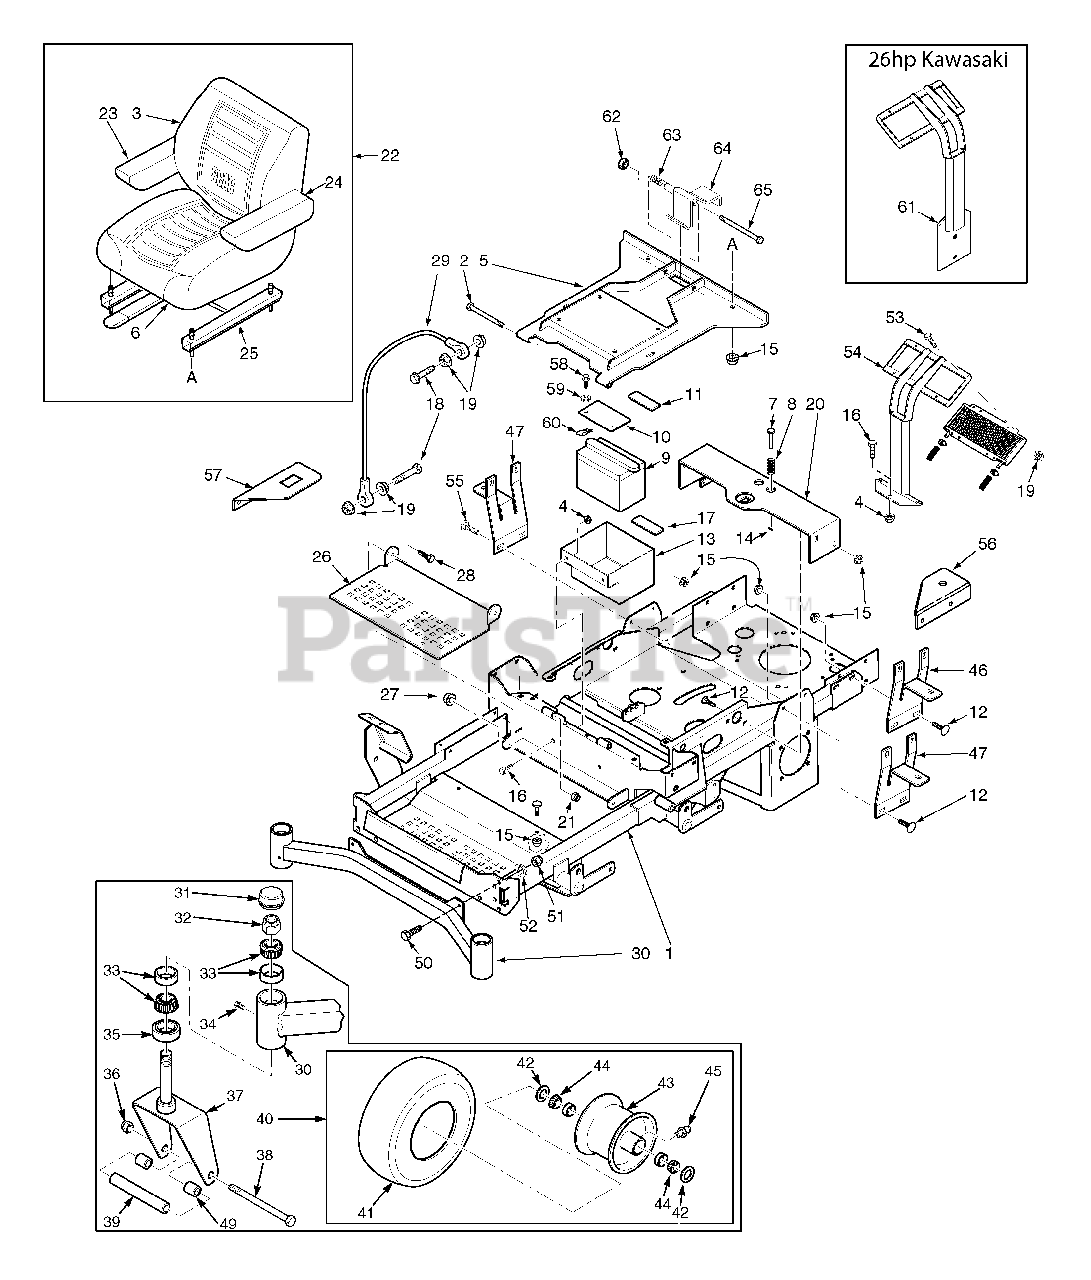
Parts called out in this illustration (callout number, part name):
1	Main Frame Assembly w/decals
2	Bolt, Hex Head 5/16-18 x 3-3/4"
3	Back Cover
4	Nut, Serr. Flange 3/8-16
5	Plate, Seat Mounting
6	Cushion Cover
7	Pin Retainer, Spring
8	Spring
9	Battery
10	Battery Cover
11	Battery Hold Down Pad
12	Bolt, Carr. 5/16-18 x 3/4"
13	Battery Box
14	Roll Pin, Spring 5/32 x 3/4"
15	Nut, Serr. Flange 5/16-18
16	Bolt, Hex Head 3/8-16 x 1"
17	Pad, Rubber
18	Bolt, Hex Head 1/4-20 x 1-1/4"
19	Nut, Serr. Flange 1/4-20
20	Seat Base Support
21	Nut, Elastic Stop 5/16-18
22	Seat Assembly w/ adj. rails and seat belt
23	Armrest Cover
24	Armrest Cover
25	Seat Track
26	Footplate
27	Nut, Elastic Stop 3/8-16
28	Bolt, Hex Head 3/8-16 x 1"
29	Cable, Seat Stop
30	Weldment, Caster Support
31	Cap, Grease
32	Nut, Elastic Stop 1.0-14
33	Bearing Set
34	Plug, 1/4-28
35	Seal, 2.0" OD x 1.625" ID
36	Nut, Elastic Stop 1/2-13
37	Yoke, Front Caster Wheel
38	Bolt, Hex Head 1/2-13 x 9-1/2"
39	Sleeve
40	Caster Wheel Assembly
41	Tire, 13 x 6.5 Smooth
43	Rim
44	Roller Bearing
45	Fitting, Grease
46	Mounting Bracket, Oil Tank
47	Mounting Bracket, Fuel Tank
48	Seat Pan
49	Spacer, Caster Wheel
50	Bolt, Hex Head 7/16-14 x 1-1/4"
51	Nut, Elastic Stop 7/16-14
52	Lockwasher, 7/16
53	Bolt, Hex Head 1/4-20 x 5/8"
54	Support Weldment, Oil Cooler
55	Bolt, Carriage 5/16-18 x 1"
56	Bracket, Fuel Valve
57	Bracket, Hour Meter
58	Bolt, Hex Head 3/8-16 x 1-1/4"
59	Lock Washer. 3/8 Spring
60	U-Nut, 3/8-16
61	Support Weld, Oil Cooler - 26hp Kaw.
62	Lock Nut, 3/8-16 Center Lock
63	Spring, Seat Latch
64	Seat Latch Weldment
65	Bolt, Hex Head 3/8-16 x 6"
